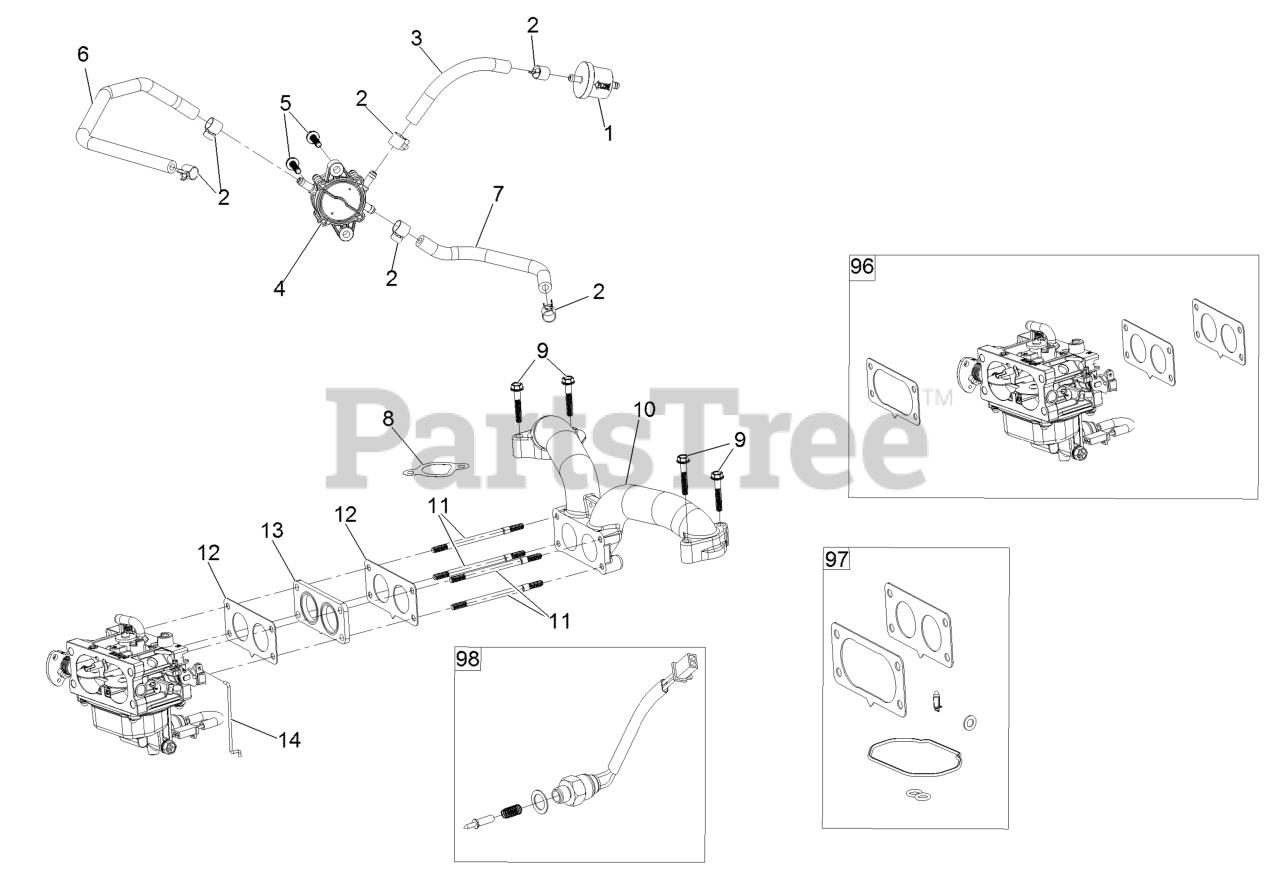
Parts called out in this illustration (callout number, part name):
1	Nut-Nyloc 3/8-16 Flg
8	Pulley-Flat, 3.50 Dia
14	Idler Arm ASM
14:2	Sleeve-Bearing
14:3	Zerk-90deg 1/4-28
14:4	Screw-HWH 5/16-18 X 3/4 Tf
21	Clutch 1.00
26	Muffler
27	Belt-V
29	Sheave-Engine
30	Anchor Clutch
32	Screw-HH W/Loctite
34	Engine-2P77F
39	Decal-708Cc V-Twin Engine
40	Decal-Drain, Oil
44	Bushing-Pivot, Idler
45	Spring-Extension
46	Washer-Spring Disc 7/16
48	Key-Machine 1/4 X 1/4 X 1
49	Screw-HWH 3/8-16 X 1 1/2 Taptite
50	Screw-HH 3/8-16 X 3 1/2
54	Bolt-Carriage 3/8-16 X 1 3/4
56	Washer-3/8 Std
57	Washer-Spring Disc 3/8
